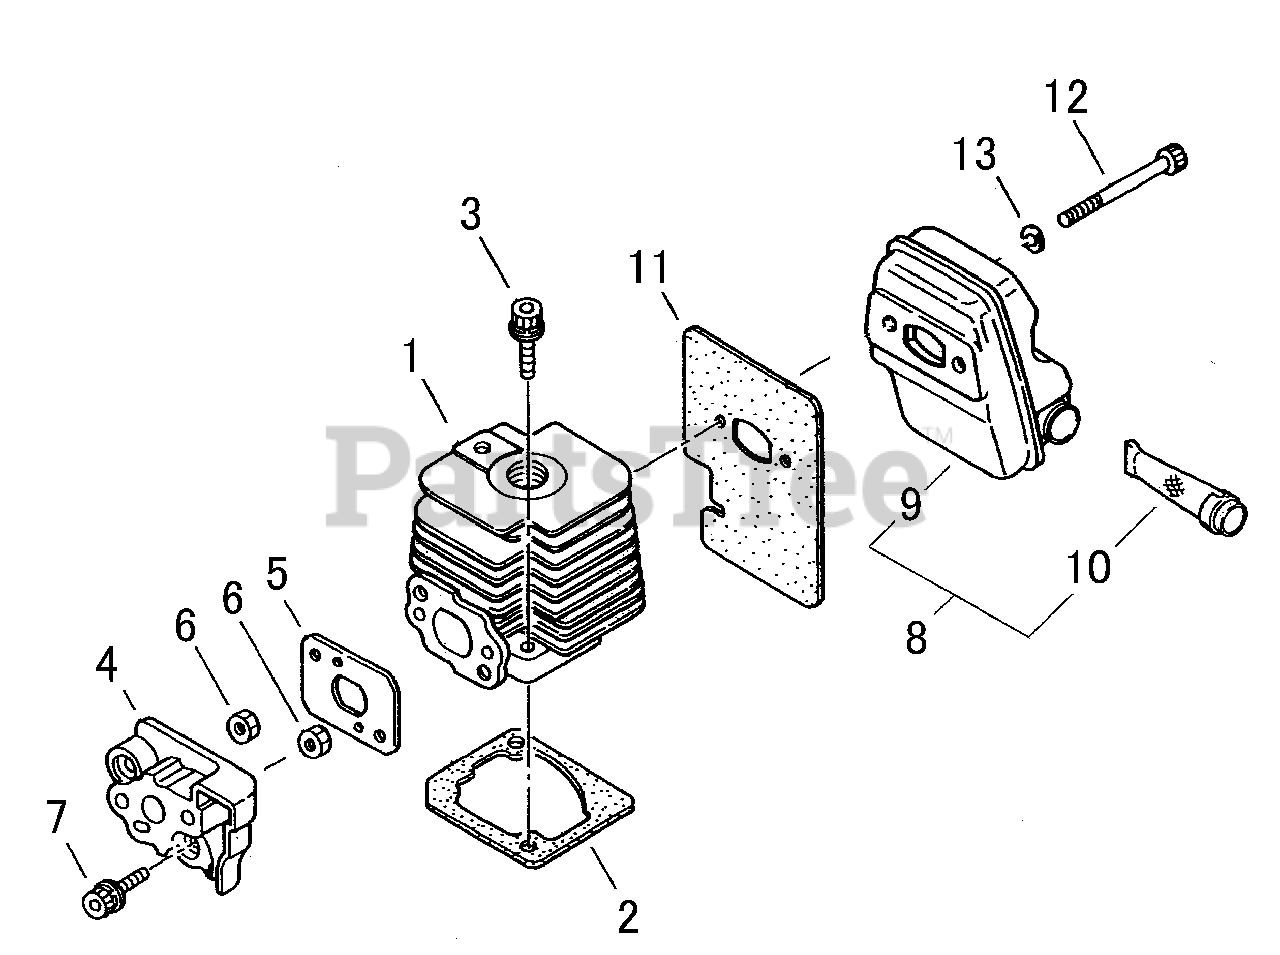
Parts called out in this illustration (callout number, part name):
1-1	CYLINDER
2	GASKET, CYLINDER
3	SCREW - 5X25
4	INSULATOR, INTAKE
5	GASKET
6	NUT - 5X6.3
7	SCREW - 5X25
8	MUFFLER ASSY
9	MUFFLER
10	SCREEN, SPARK ARRESTOR
11	SHIELD, EXHAUST
12	SCREW - 5X40
13	WASHER - 5
